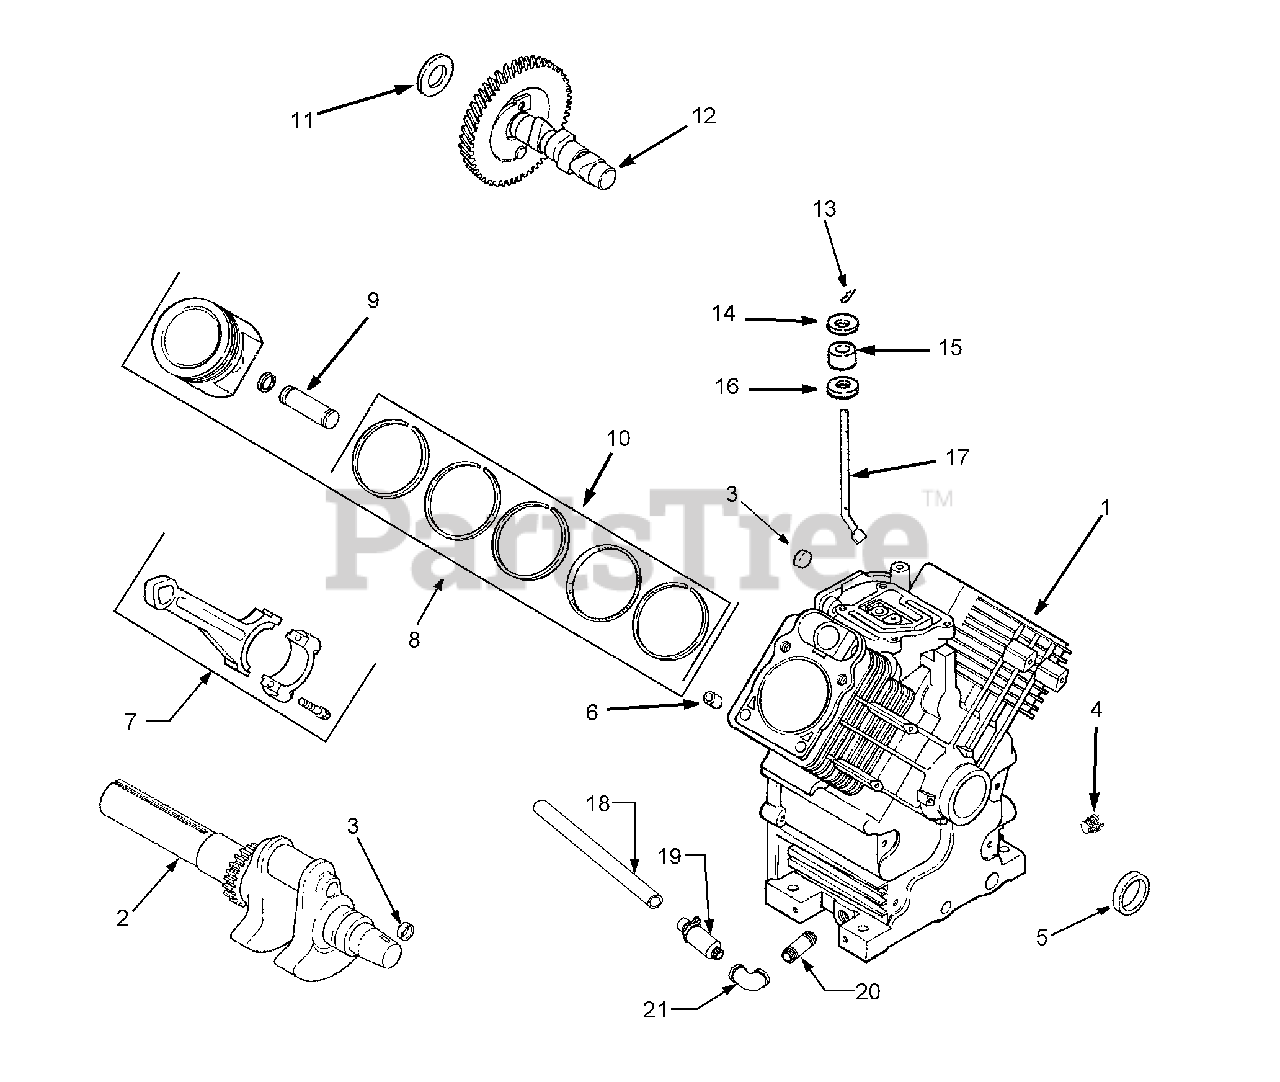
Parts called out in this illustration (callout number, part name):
1	Engine, Complete
2	Crankshaft
3	Plug, Cup
4	Plug, Hex Head, 3/8 NPTF
5	Seal, Oil
6	Pin, Dowel Locating
7	Rod, Connecting, Std
8	Piston w/Ring Set, Std
9	Retainer, Piston Pin
10	Ring Set, Std
11	Shim, Camshaft, .0320
12	Camshaft
14	Washer, Plain
15	Seal, Governor Cross Shaft
16	Washer, Plain
17	Shaft, Governor Cross
18	Hose, Oil Drain
19	Drain, Oil
20	Pipe, Straight
21	Elbow, 90°.
